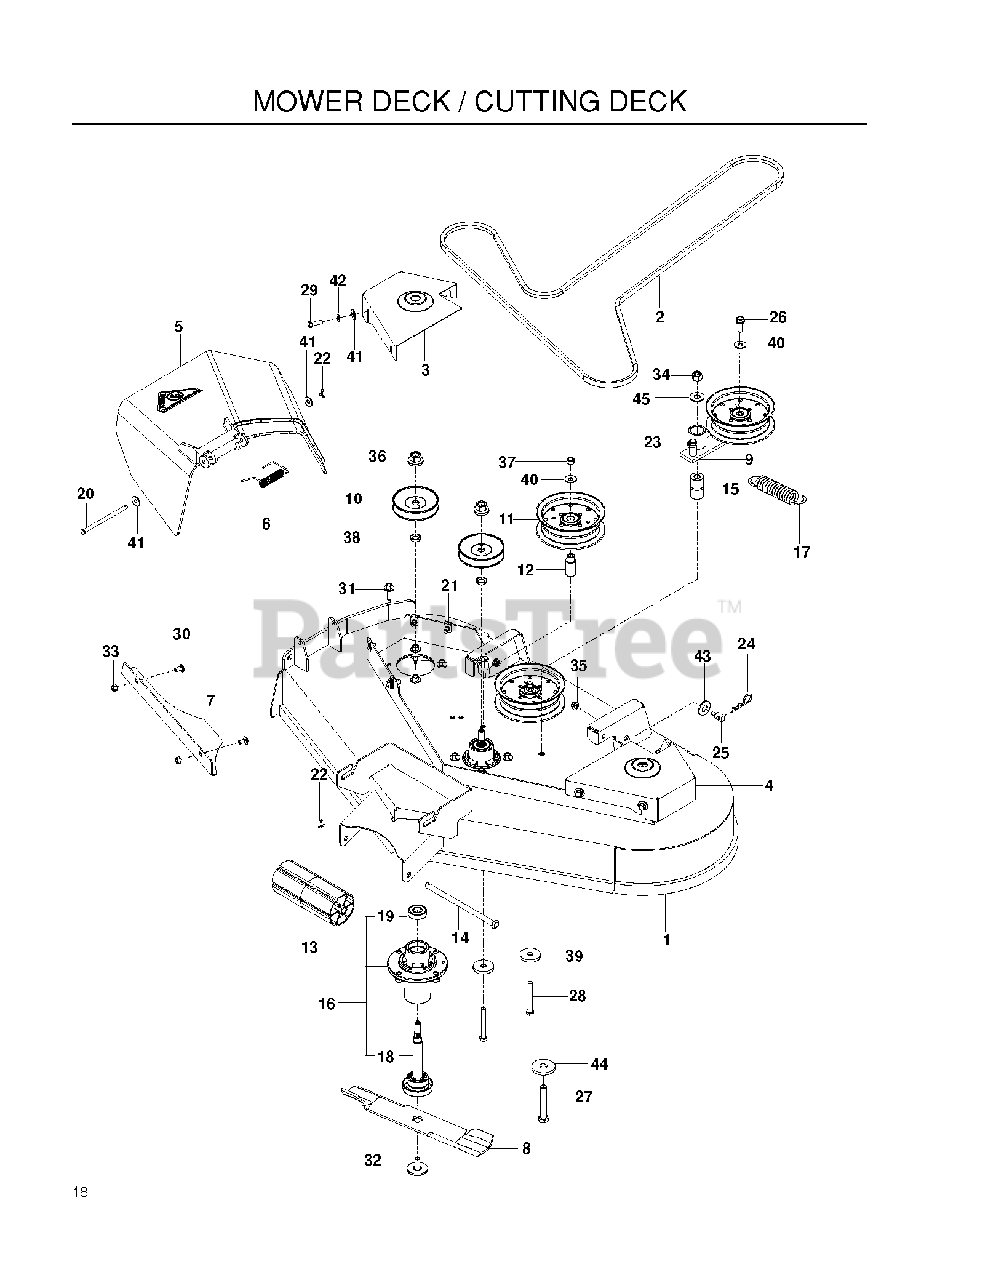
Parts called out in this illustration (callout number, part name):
1	DECK SVC W/DECALS 42 RZ ORANGE
3	BELT SHIELD, RIGHT 42, ORG
4	BELT SHIELD, LEFT 42, ORG
5	DISCHARGE CHUTE 42"
6	SPRING - TORSION
7	CONFINEMENT.PLATE.42".BLACK
8	BLADE, 14 5/8"
10	PULLEY, MADREL 3.70 OP
11	PULLEY, IDLER
12	IDLER BUSHING
13	NOSE ROLLER 48"
14	ROD.ROLLER.NOSE.NARROW.48"
15	PIVOT BUSHING
16	MANDREL.DECK.ASSEMBLY
18	GREASABLE MANDREL SHAFT
19	BEARING, BALL
20	PIN-CLEVIS 5/16 DIA X 5.19 ZD
21	U-CLIP 5/16-18 NUT RETAINER
22	RP_COTTER PIN 1/8 X 3/4
23	ZERK
24	HAIRPIN #4
25	STUD.FASTNER.W/ANTI-ROTATE
26	4CS 3/8C X 1 SERRATED HEAD
27	HCS 1/2C X 3 1/4
28	HCS 3/8C X 3
29	HCS 5/16C X 1
30	CARRIAGE BOLT 5/16C X 5/8"
31	WASHER HEAD SCREW
32	BLADE BOLT ASSY-7/16" TB REPL
33	NUT 5/16 NYLOC
34	RP NUT 1/2-13 HEX NYLOC ZD
35	5/16-18 NYLOC FLANGE NUT
36	LOCKNUT - 9/16
37	NUT 3/8-16 NYLOC
38	WASHER-SPACER
39	SPINDLE WASHER
40	RP WASHER 3/8 FLAT
41	WASHER 5/16 FLAT
42	WASHER 5/16 LOCK
43	WASHER 5/8 FLAT
44	WASHER, SUPPORT
45	WASHER 1/2 FLAT
